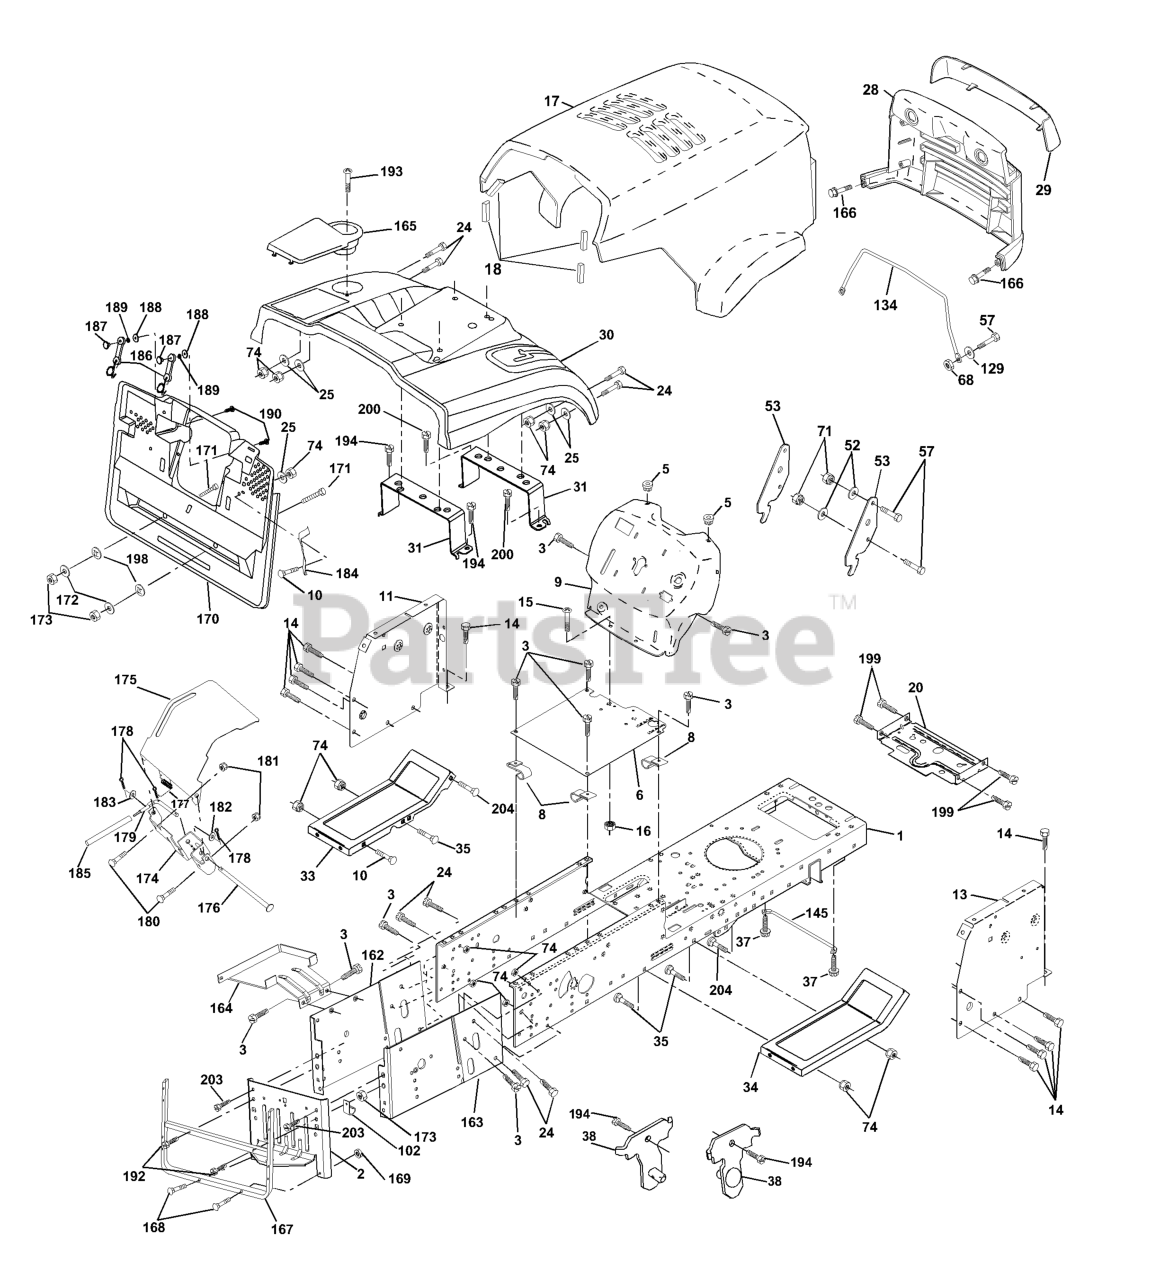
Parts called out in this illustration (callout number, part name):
1	CHASSIS STAMPING
3	SCREW
5	BUMPER.RUBBER.HOOD
6	SADDLE FLAT
8	CLIP,INSULATOR
10	BOLT
11	PANEL DASH LH
13	PANEL DASH
14	SCREW
15	SCREW
16	NUT
17	HOOD
18	BUMPER HOOD T
20	PLATE MTG
24	BOLT
25	BOLT
28	GRILL
29	LENS
30	FENDER
31	BRACKET SUPPORT FENDER
33	FOOT REST LH
34	FOOTREST RH
35	BOLT
37	SCREW
38	BRACKET
52	WASHER
53	BRACKET PNT PICK OFF LT/PL
57	BOLT
68	NUT
71	NUT
74	NUT
102	CLIP T
129	WASHER
134	ROD SUPPORT HOOD LT/PL HUS.
145	ROD PIVOT CHASSIS/HOOD
165	COVER BATTERY
166	SCREW
167	SUPPORT.ASM.BACKPLATE
168	BOLT
169	NUT LOCK
170	COVER BACKPLATE
171	BOLT
172	WASHER
173	NUT
176	HINGE PIN
177	SPRING COVER LH
178	PIN COTTER
180	BOLT
181	NUT
182	WASHER
183	WASHER
185	TUBE LEVER
186	LATCH ASSY
187	NUT
188	WASHER
189	WASHER
190	SCREW
192	SCREW
193	SCREW
194	SCREW
199	SCREW
200	SCREW
203	SCREW
204	SCREW
